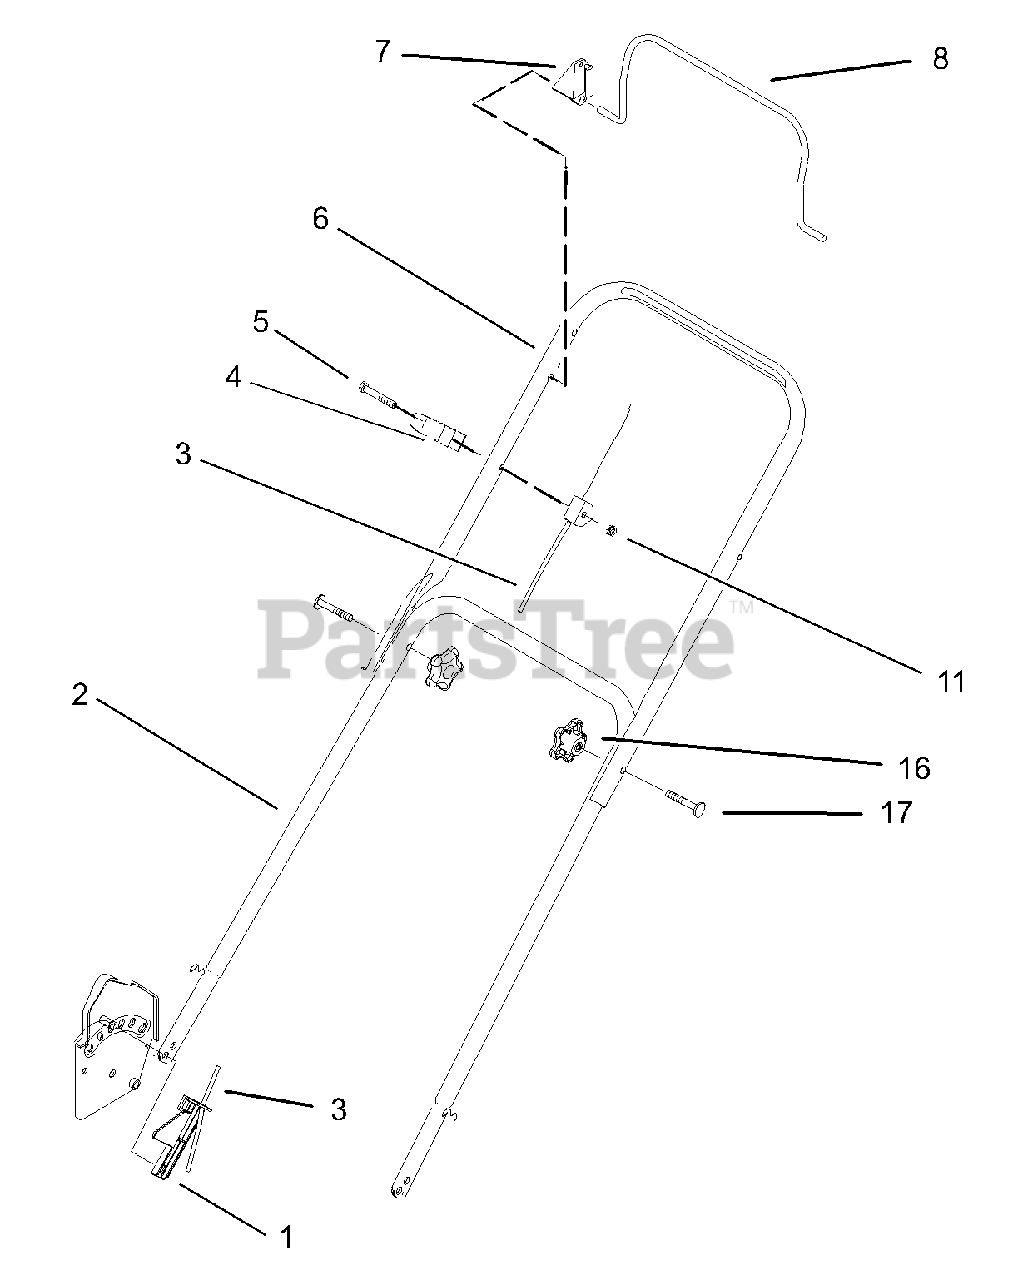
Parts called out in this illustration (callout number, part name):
1	Guard-Cable
2	Handle-Lower
3	Brake Cable ASM
4	Guide-Rope
5	Screw-HH
6	Handle-Upper
7	Stop-Pivot
8	Bail-Brake
11	Nut-Lock, NI
16	Knob-Handle
